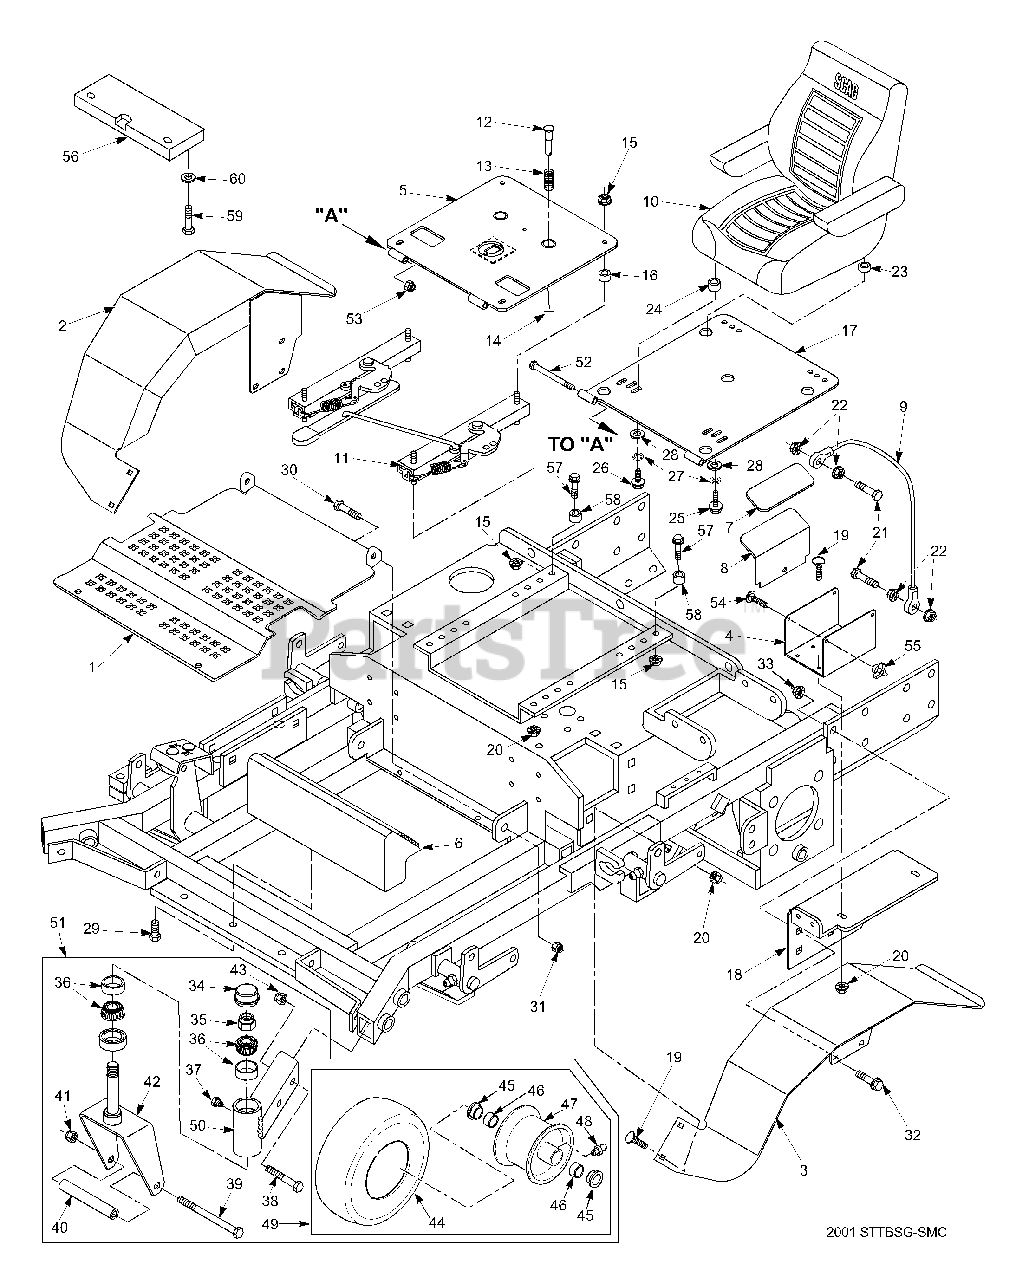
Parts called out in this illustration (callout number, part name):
1	Footplate
2	Fender, RH
3	Fender, LH
4	Box, Battery
5	Plate, Lower Seat
6	Footrest
7	Insulation, Battery Cover
8	Cover, Battery
9	Cable, Seat Stop
10	Seat
11	Track Set, Seat Adjuster
12	Pin, Spring
13	Spring, Seat
14	Spring Pin, .156 x .75"
15	Nut, Serr. Flg. 5/16-18
16	Spacer
17	Plate, Upper Seat
18	Bracket, Battery
19	Bolt, Carr. 5/16 -18 x .75"
20	Nut, Serr. Flg. 5/16-18
21	Bolt, Hex Head 1/4-20 x 1.25"
22	Nut, 1/4-20
23	Spacer
24	Spacer
25	Bolt, Hex Head 5/16-18 x 1.5"
26	Bolt, Hex Head 5/16-18 x 2.25"
27	Lock Washer 5/16"
28	Flat Washer 5/16 .375 x .875 x .083
29	Bolt, Hex Head 1/2-13 x 1.5"
30	Bolt, Hex Head 3/8-16 x 1.0"
31	Nut, Elastic Stop 3/8-16
32	Capscrew, Serr. Flng. 3/8-16 x 1.00"
33	Nut, Serr. Flng. 3/8-16
34	Cap, Grease
35	Nut, Hex Elastic Stop 1.0-14
36	Bearing w/ Race
37	Plug, 1/4-28 THD Form
38	Bolt, Hex Head 5/8-11 x 4.00"
39	Bolt, Hex Head 1/2-13 x 7.5"
40	Spacer
41	Nut, Hex Head Elastic Stop 1/2-13
42	Yoke Weldment, Caster
43	Nut, Elastic Stop 5/8-11
45	Bearing, Oilite
46	Bearing, Roller
47	Rim Assembly
48	Fitting, Grease
49	Wheel Assembly
50	Extension, Caster Wheel LH, 61"
51	Caster Wheel Assembly LH, 61" Adv.
52	Bolt, Hex Head 5/16-18 x 3.50"
53	Nut, Hex Head Elastic Stop 5/16-18
54	Bolt, Carriage 1/4-20 x 6.00"
55	Wing Nut 1/4-20 x .75"
56	Weight
57	Bolt, Hex Head 5/16-18 x 1.75"
58	Spacer
59	Bolt, Hex Head 1/2-13 x 3.5"
60	Flat Washer 1/2-.562 x .1.375 x .109
